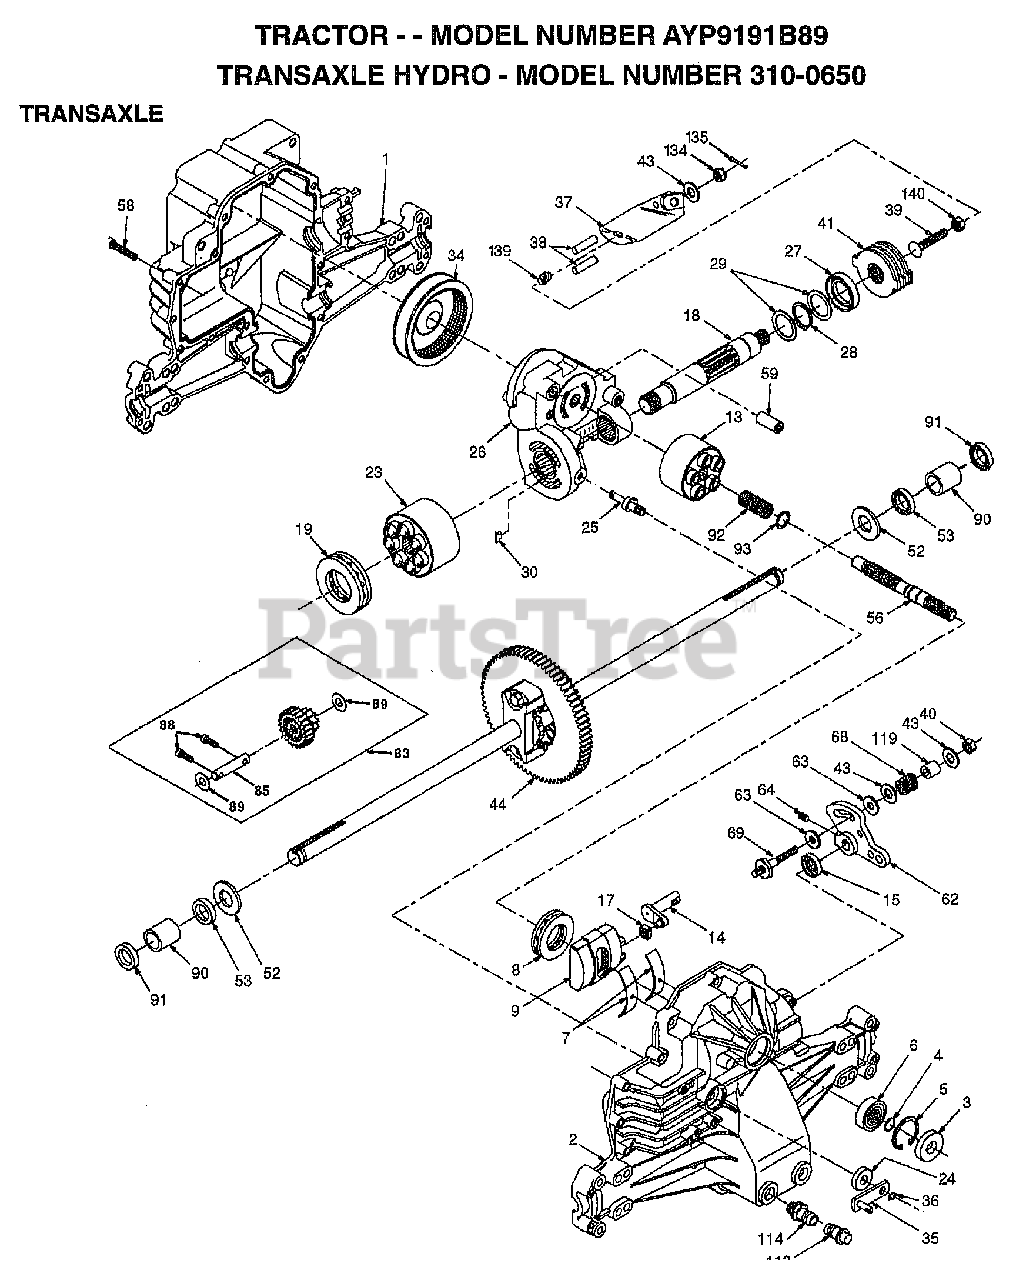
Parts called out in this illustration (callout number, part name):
1	HOUSING.L.50074RM
2	HOUSING.UP.70125
3	SEAL.9008000-0128
4	RING.RET.2003016.
5	RING.RET.2003052.
6	BEARING.(50552)42X68X16
7	CRADLE- 2003023.
8	BEARING.THU.50551
9	SWASHPLT.2003087.
13	BLOCK.CLYN.70079.
14	ARM.TRUN.2003005.
15	SEAL.9008000-0126
17	GUIDE.2000015.
18	SHAFT.MOTOR.50449
19	BEARING.THU.50552
23	BLOCK.CYLIN.70082
24	SEAL.LIP.45074
25	ACTUATOR.2003555
26	KIT.CEN.SEC.70250
27	SEAL.LIP.45075
28	RING RETAIN 50007
29	WASHER.44872
30	PLATE.BYP.2003554
34	ELEMENT.OIL.44964
35	ARM.BYPASS.50270
36	RING.RETAIN.44870
37	ARM.ACTUAT.23710
38	PIN.ACTUAT.44891
39	BOLT.50316
40	NUT.LOCK.HX.50317
41	KIT.BRAKE.70135
43	WASHER HYD 44130
44	DIFFRENTIAL.70226
52	WASHER.HYD.44875
53	SEAL.HYDRO.45076
56	SHAFT.INPUT.50005
58	BOLT.1/4-20.44876
59	PIN.HYDRO.50002
62	ARM.CONTROL.50254
63	PUCK.DAMPER.50281
64	SCREW.SET.50018.
68	SPRING.HYD.50277
69	STUD.5/16-24.DANA
83	JACKSHAFT/PINION GEAR.70132
85	PIN.SHAFT 50559
88	SCREW.CAP.50154.
89	WASHER.HYD.50132
90	BEARING.SLV.50118
91	SEAL.WIPER.50941
92	SPRING.2003014.
93	WASHER.2003017
113	CAP.VENT.70109
114	O-RING.ASM.70110
119	SPACER.HYD.50278
134	NUT.CAS.HYD.44142
135	PIN.COT.HYD.44101
139	SPRING.COMP.50431
140	NUT.HEX.50269
